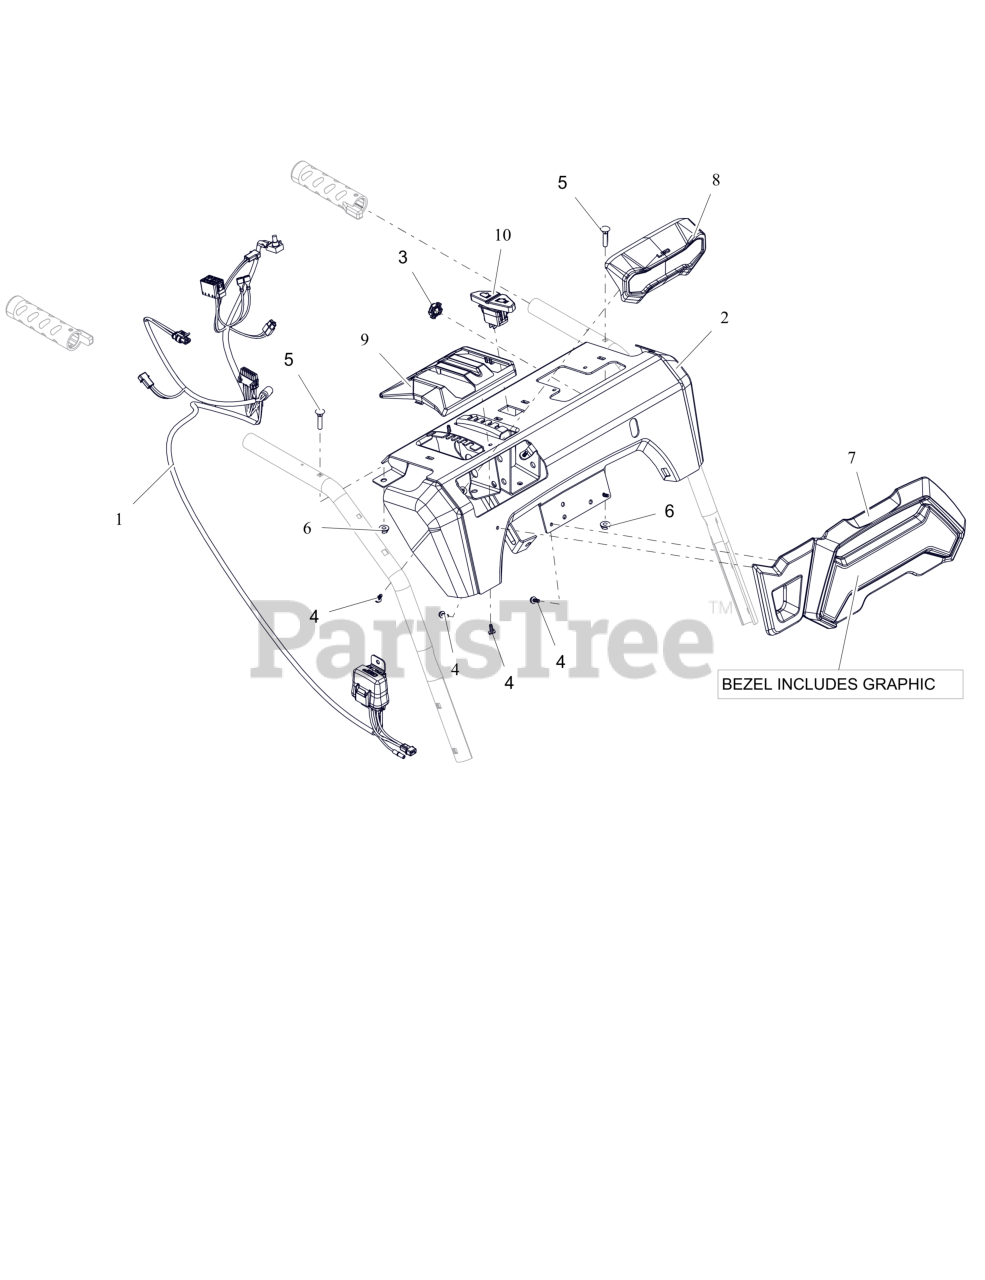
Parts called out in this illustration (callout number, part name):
1	HARNESS- WIRE - LT HG EFI
2	PANEL, CONTROL-EFI ID W/DECAL
3	CRANK BUSHING, NYLON CHUTE BK
4	SCR, PLASTIC #10X.50
5	BLT-RDHDXLSQNK.25-20X1.25 G5ZC
6	NUT-LK-CTR-FLG .25-20 ZC120
7	BEZEL, LARGE - DELUXE
8	HEADLIGHT ASM- LED
9	BEZEL, SHIFT - FRICTION
10	SWITCH- ROCKER SPST-ON/OFF
